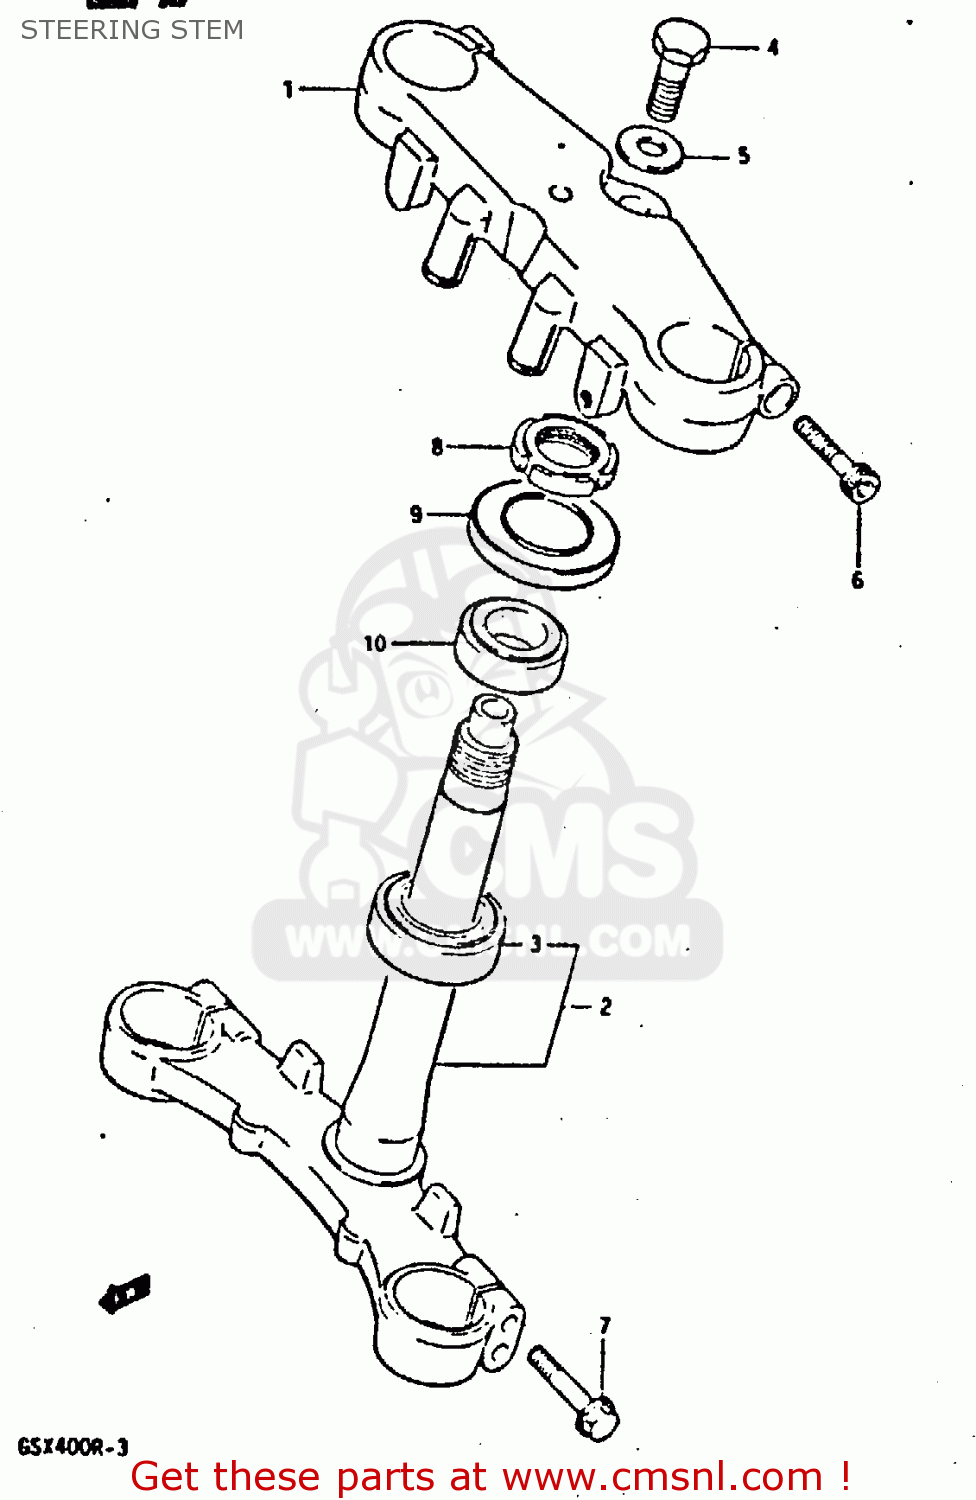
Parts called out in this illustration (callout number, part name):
1	HEAD.STEERING S
2	STEM.STEERING
3	BEARING
4	BOLT,STEERING STEM HEAD
5	WASHER
6	BOLT, REAR (8X30)
7	BOLT
8	NUT,STEERING STEM(25X44X10)
9	SEAL OIL
10	TAPER,ROLLER BEARING
